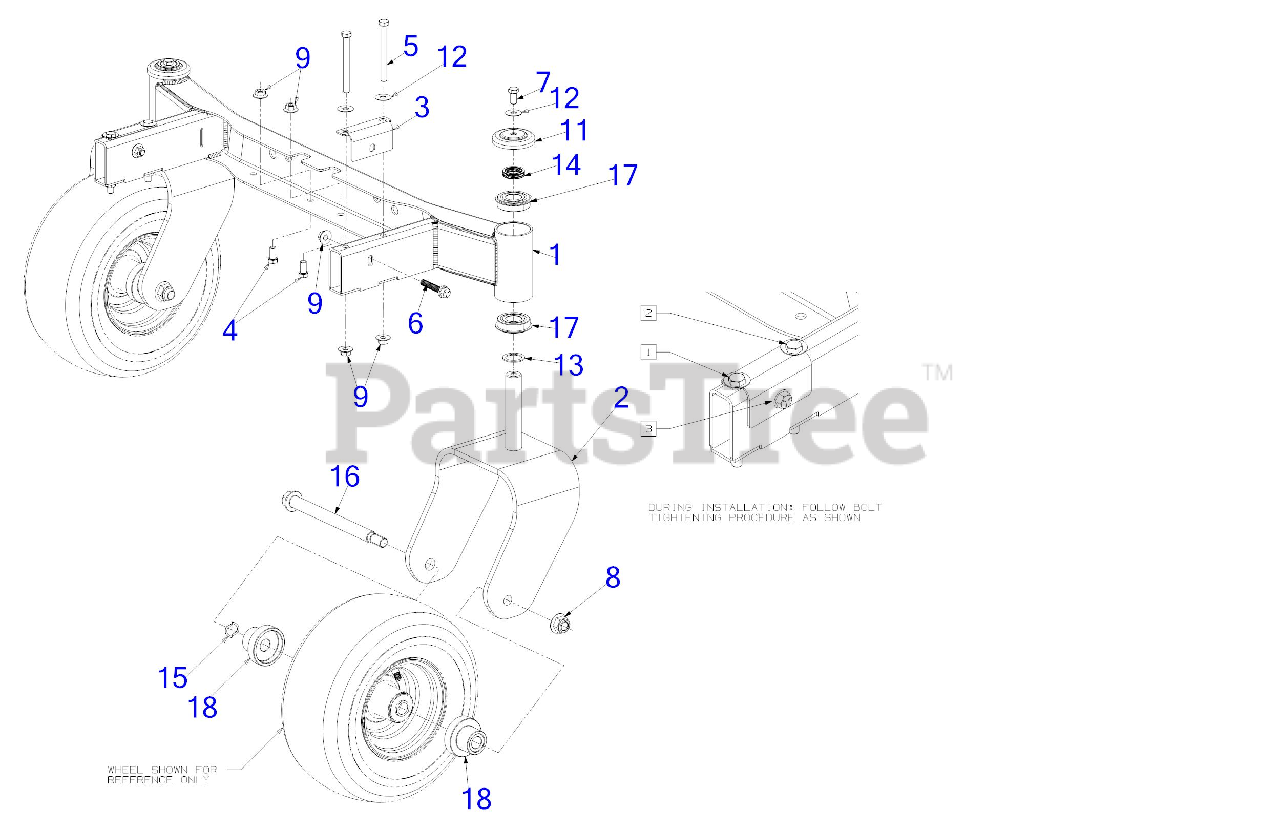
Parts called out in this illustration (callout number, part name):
4	HEX SCREW 3/8-16 x .75
5	SCREW 3/8-16 x 3.75 GR5
6	SCREW 3/8-16 x 2.00 GR5
7	SCREW 3/8-16 x .75 GR 5
8	FLANGE LOCK NUT
9	FLANGE LOCK NUT
11	AXLE CAP 2.375
12	FLAT WASHER
13	FLAT WASHER 1.015X1.375X.062
14	WAVE WASHER
15	WAVE WASHER 1.115:0.750:.200
16	SHOULDER BOLT
17	BALL BEARING
18	HUB: 0.76 X 1.56 X 1.25
